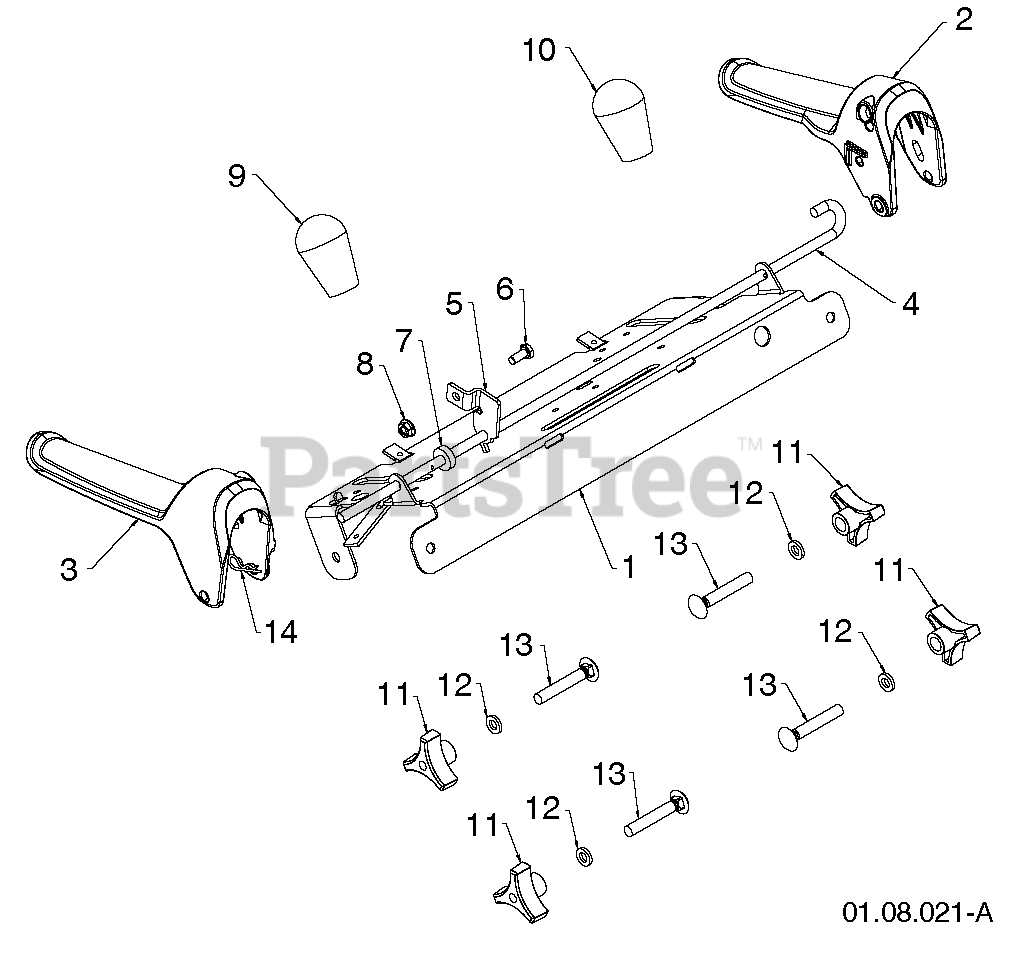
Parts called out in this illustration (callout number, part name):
1	PANEL.CONTROL.SNOW.BLACK
2	LEVER.CONTROL.LH.PL.BLACK
3	LEVER.CONTROL.RH.PL.BLACK
4	BAIL.CONTROL.INTERLOCK.SNOW
5	ARM.IMPELLER.ROD.
6	BOLT
7	SPACER.CONTROL.LEVER
9	KNOB LEVER, BLACK
10	RED KNOB SHIFTER
11	KNOB.HANDLE.3/8.TRI-POINT.BLAC
13	BOLT 3/8-16 X 2-1/4
14	SPRING RETAINER
